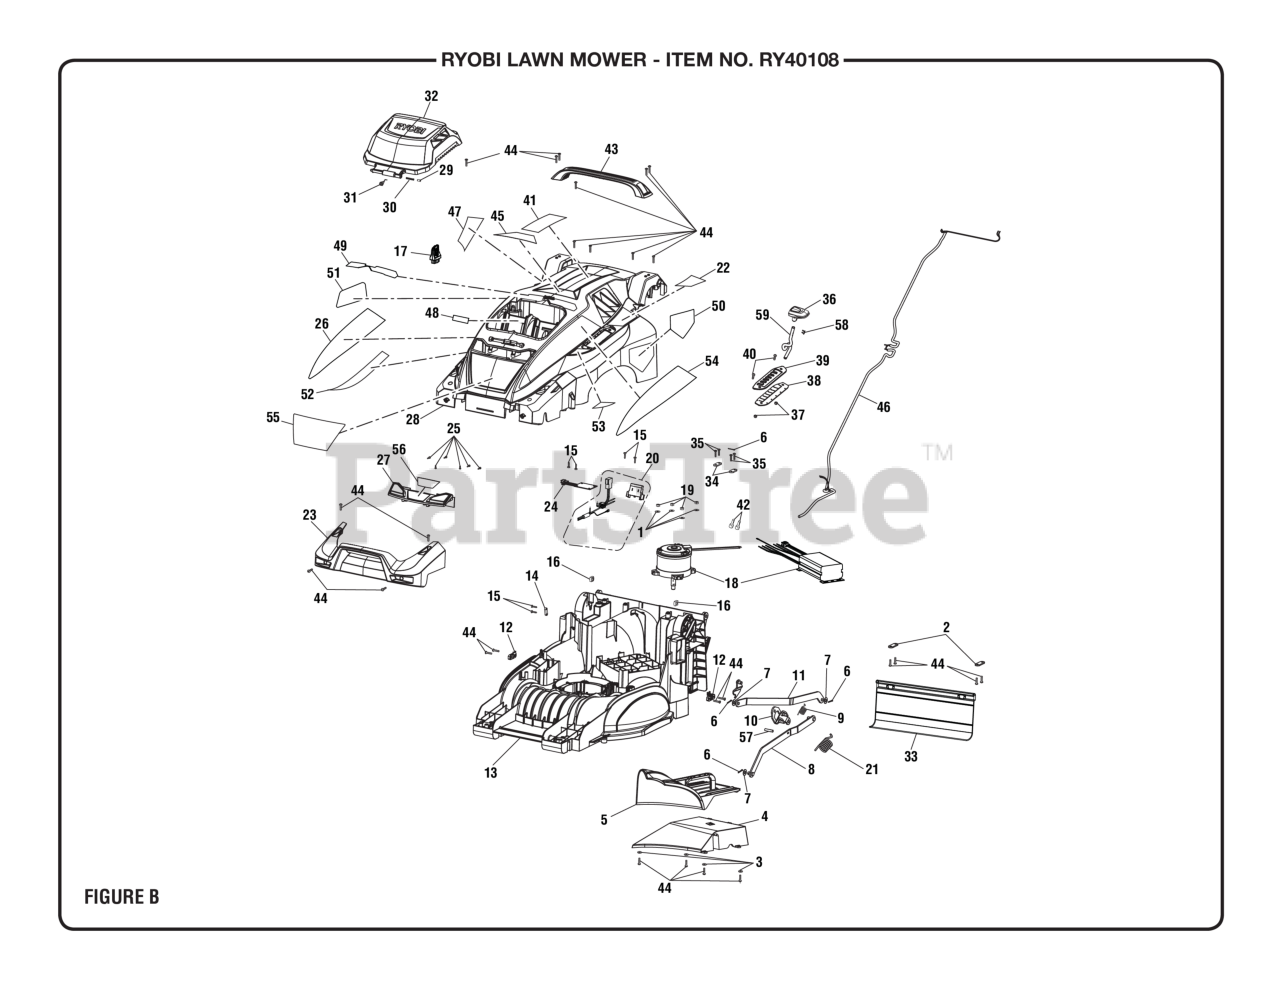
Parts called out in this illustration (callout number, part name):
1	Washer (ID6.2 x OD15 x 0.08t)
2	Axle Pressure Plate
3	Washer (ID4.5 x OD10 x 1t)
5	Mulching Plug
6	Cotter PinÏ? (2.5)
7	Washer (ID8.4 x OD18 x 1t)
8	Front Lift Rod
9	Torsion Spring (Height Adjustment)
10	Height Adjustment Bracket
11	Rear Lift Rod
12	Axle Mount
13	Deck
14	Wire Press Plate
15	Screw (M4 x 16 mm, T20 Torx Pan Hd.).
16	Square Nut (M8)
17	Start Key
18	Motor and Controller Assembly (EU17301, A.D.C. Week 30, 2017)
19	Lock Nut (M6)
20	Key Holder Assembly
21	Rentention Spring
22	Height Adjustment Label
23	Front Bumper
24	Circuit Board (EU17171, & After A.D.C. Week 17, 2017 Light Assembly)
25	Screw (M3 x 8 mm, Pan Hd., Pan Hd)
26	Brushless Label (Right)
27	Light Assembly w/Label
28	Deck Cover
29	Battery Door Axle
30	Compression Spring
31	Battery Cover Spring
32	Battery Cover
34	Pressure Plate (Height Adjustment)
35	Screw (M4 x 18 mm, T20 Torx Pan Hd.)
36	Height Adjustment Handle
37	Lock Nut (M5 x 0.8 mm)
38	Shifter Boot
39	Height Adjustment Plate
40	SCREW (M5 x 16 mm SOC. WASHER HD. CAP)
41	Bilingual Danger (French/Spanish) & Trilingual Warning (English/French/Spanish) Label
42	Terminal Block w/Screw
43	Carrying Handle
44	Screw (M4 x 20 mm, T20 Torx Pan Hd. S.T.)
45	Danger/Warning Icon Label (English)
46	Wiring Harness (EU17301 & After, A.D.C. Week 30, 2017)
47	40V Lithium Label
48	On Board Battery Storage Label
49	Start Key Label
50	Danger Label (No Hands/Feet)
51	Data Label
52	RYOBI Label (Right)
53	Logo Label
54	Brushless Label (Left)
55	40V Brushless Logo Label
56	LED Headlight Label
57	Axle (Height Adjustment)
58	Screw (M3 x 9 mm, Flat Hd.)
59	Lever Arm
